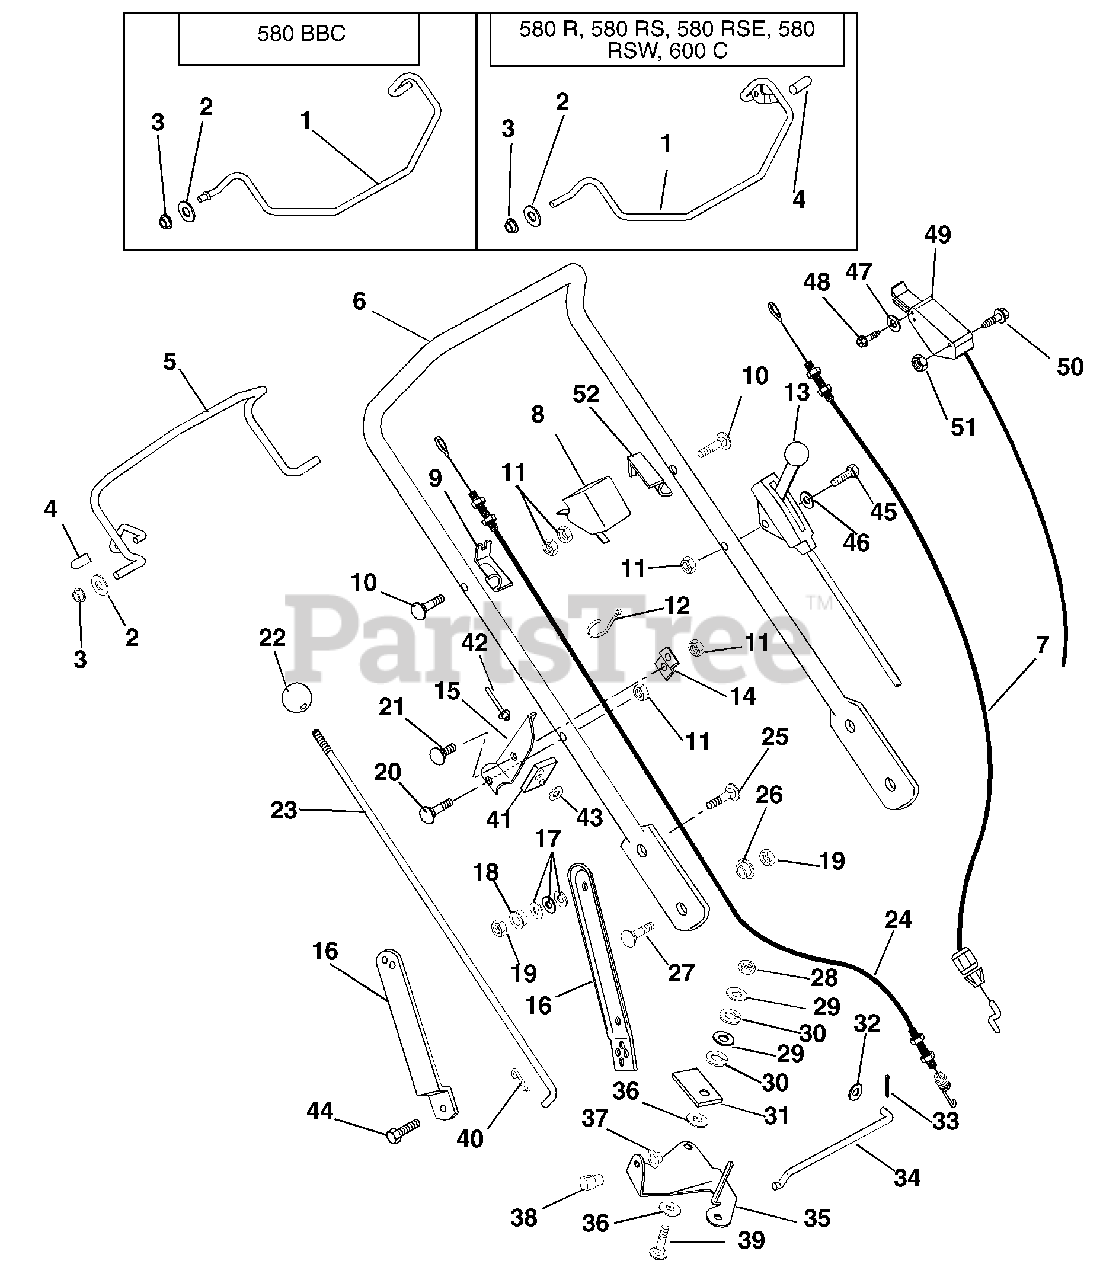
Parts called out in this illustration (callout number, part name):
1	Engine Bail Weldment
1	Bail- Blade Brake/Clutch
2	Washer-Flat-Steel .32 x .44 x .44 x .56
3	Bushing-Flange .325 x .688 x .560
4	Cap, Vinyl .25 I.D.
5	Traction Bail
7	Engine Control Cable
8	Switch-Cable Anchor
9	Cable Anchor-Right Hand
10	Bolt-Round Head Square Neck .25-20 x 1.25
11	Nut-Locking-Center .25-20
13	Throttle Cable
14	Brace-Speed Control
15	Bracket-Speed Control
16	Link-Handlebar Adjuster Left Hand
16	Link-Handlebar Adjuster Right Hand
16	Handlebar Bracket
17	Washer-Bellville Spring
18	Bushing-Flange .325 x .50 x .513 x .875
19	Nut-Locking-Center .31-18
20	Bolt-Round Head Square Neck .25-20 x 1.38
21	Bolt-Round Head Square Neck .25-20 x .50 Grade 5
23	Rod-Speed Control
24	Traction Cable
25	Bolt-Round Head Square Neck .31-18 x 1.00 Grade 5
26	Shoulder Spacer
27	Bolt-Round Head Square Neck .31-18 x .75 Grade 5
27	Bolt-Round Head Square Neck .31-18 x 1.00 Grade 5
28	Nut-Locking-Center .38-16
29	Washer-Flat-Steel .406 x .812 x .065
30	Washer-Lock .375 x .115 Heavy
31	Pressure Flange
32	Washer-Flat-Steel .281 x .620 x .065
33	Pin-Cotter .06 x .50
34	Shift Link
35	Bell Crank-Speed Control
36	Friction Washer
37	Cap,
39	Bolt-Round Head Square Neck .38-16 x 1.25
40	Pin-Hair-Internal .08 x .18 x 1.18
41	Support Pad
42	Rivet .187 x .575
43	Washer-Flat Steel .219 x .50 x .049
44	Bolt-Hex .31-18 x .75 Grade 5
45	Bolt-Round Head Square Neck .25-20 x 1.75 Grade 5
45	Bolt-Round Head Square Neck .25-20 x 1.75 XL
46	Washer-Flat-Steel .250 x .562 x .049
46	Washer-Flat-Steel .281 x .62 x .065
47	Washer-Flat-Steel .219 x .50 x .049
48	Screw-Tapping 10-24 x .50 Hex Washer Head
49	Control- Blade Brake/Clutch
50	Screw-Machine 10-24X2.00 Hex Washer Head
51	Nut-Hex 10-24
52	Cable Anchor-Left Hand
